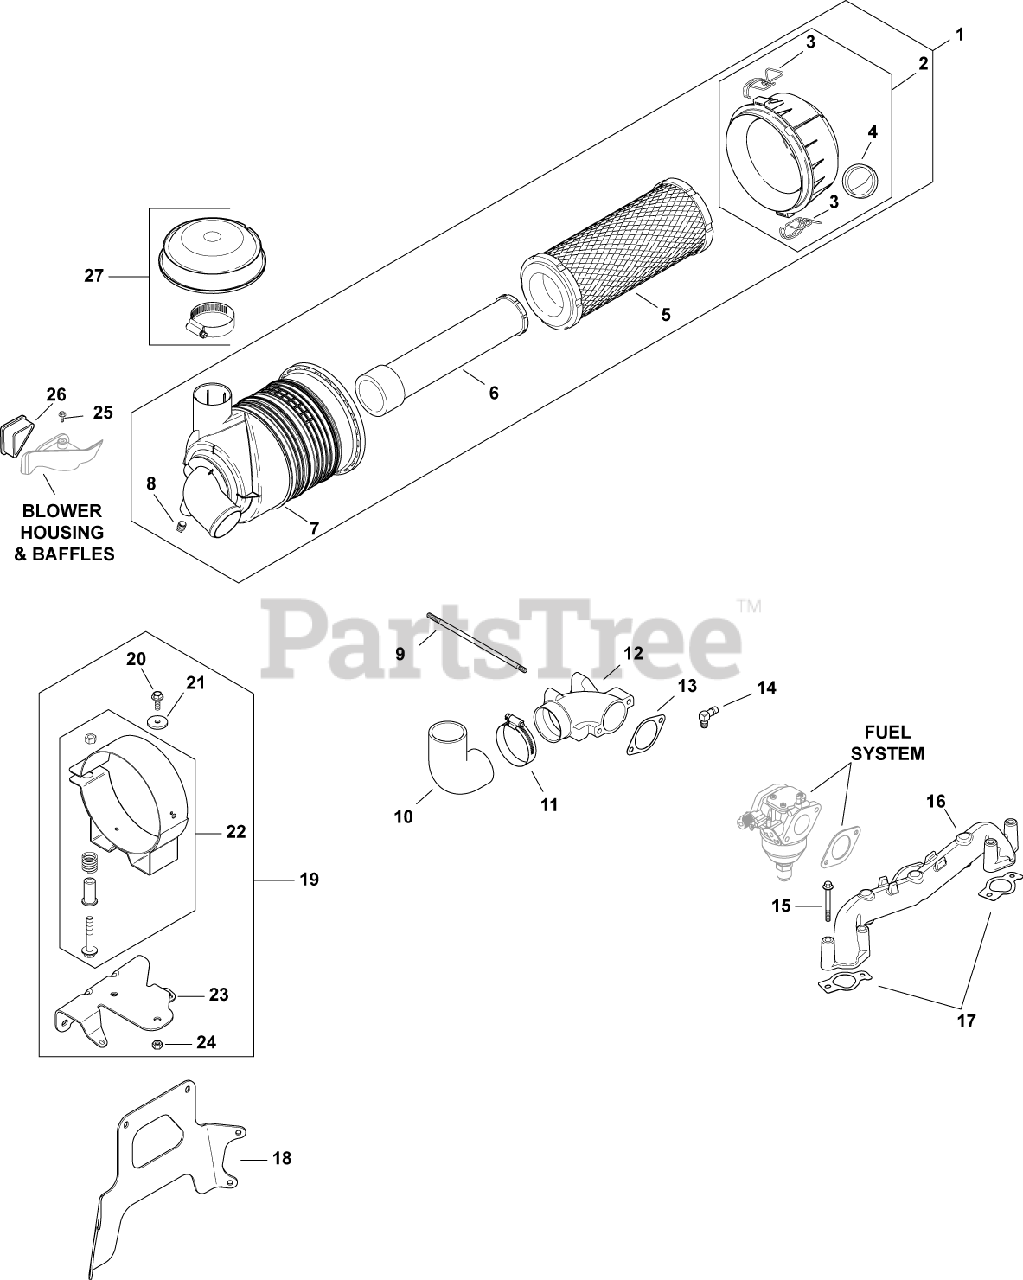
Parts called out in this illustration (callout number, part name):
1	AIR CLNR, CANISTER-USE 25 048 17-S
2	COVER ASSEMBLY, AIR CLEANER
3	CLIP - USE 62 154 07-S
4	VALVE, DUST EJECTOR
5	ELEMENT, AIR FILTER - PRIMARY
6	ELEMENT, AIR FILTER - SAFETY
7	HOUSING, HD AIR CLEANER
8	PLUG, PIPE
9	STUD, M6X1.0X180
10	HOSE, AIR CLEANER
11	CLAMP, HOSE
12	ELBOW, AIR CLEANER
13	GASKET, AIR CLEANER BASE
14	CONNECTOR, HOSE
15	SCREW, HEX SOCKET HEAD CAP
16	MANIFOLD, INTAKE
17	GASKET, INTAKE MANIFOLD USE 24 041 79-S
18	BRACKET, MAIN SUPPORT-USE 24 126 185-S
19	BRACKET, AIR CLEANER -USE 24 126 186-S
20	SCREW, FLG M6X1.0X16
21	WASHER, FLAT 1/4" (O.D. 1")
22	BRACKET, AIR CLEANER-USE 24 126 191-S
23	BRACKET, AIR CLEANER-USE 24 126 184-S
24	NUT, LOCK M6X1.0
25	SCREW, WSH HD TAP #8-18X1/2"
26	COVER, BLOWER HOUSING USE 24 096 160-S
27	HOOD, AIR CLEANER (5.25)-USE 25 324 04-S
